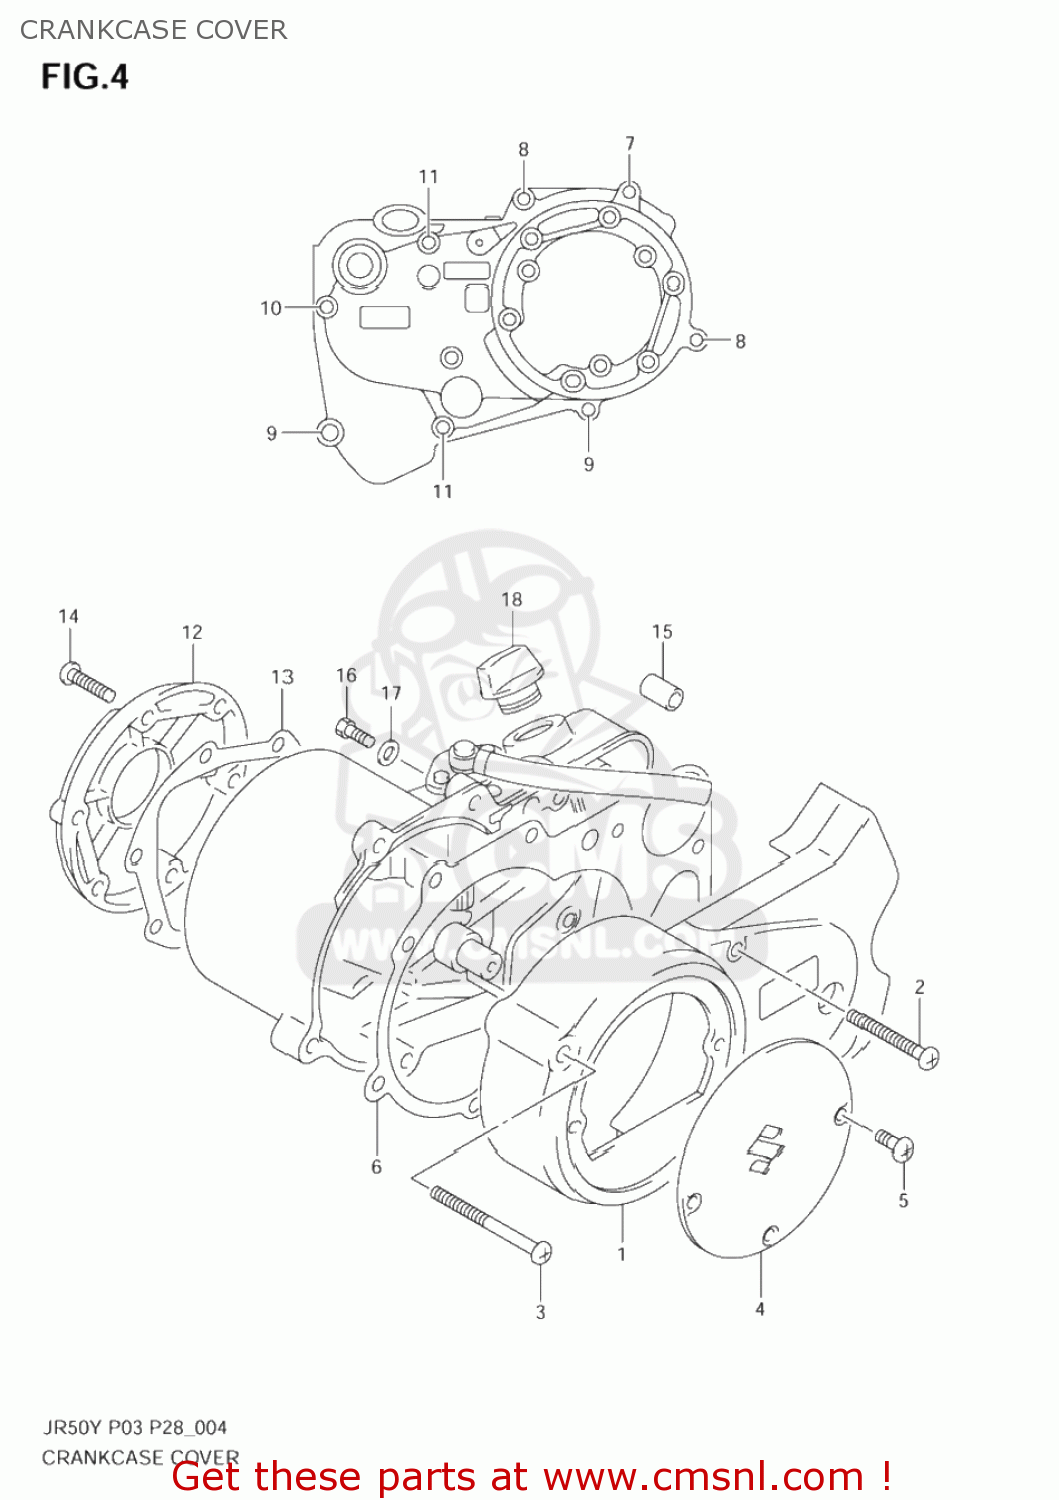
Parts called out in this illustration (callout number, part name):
1	COVER,MAGNETO
2	SCREW
3	SCREW
4	CAP,MAGNETO INSPECTION
5	SCREW 4X6
6	GASKET,CLUTCH COVER (NAS)
7	SCREW, 6X20
8	SCREW
9	SCREW 6X30
10	SCREW
11	SCREW
12	CAP,CLUTCH RELEASE ADJUST
13	GASKET,CL RLSE ADJ CAP (NAS)
14	SCREW, 6X20
15	PIN
16	SCREW(6X10)
17	GASKET(6.2X11X1).2 (NAS)
18	PLUG SET
